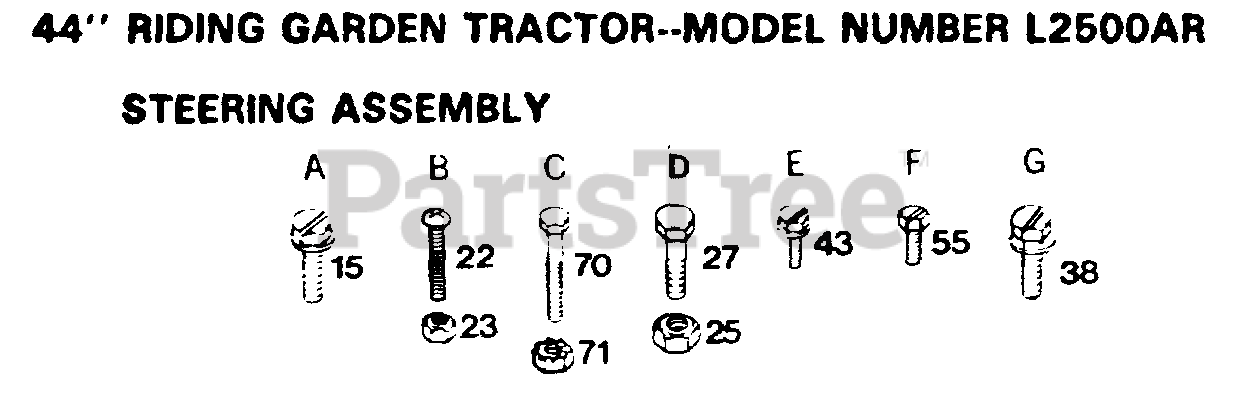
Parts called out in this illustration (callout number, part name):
15	SCREW
22	SCREW
38	SCREW LT
43	SCREW LT
